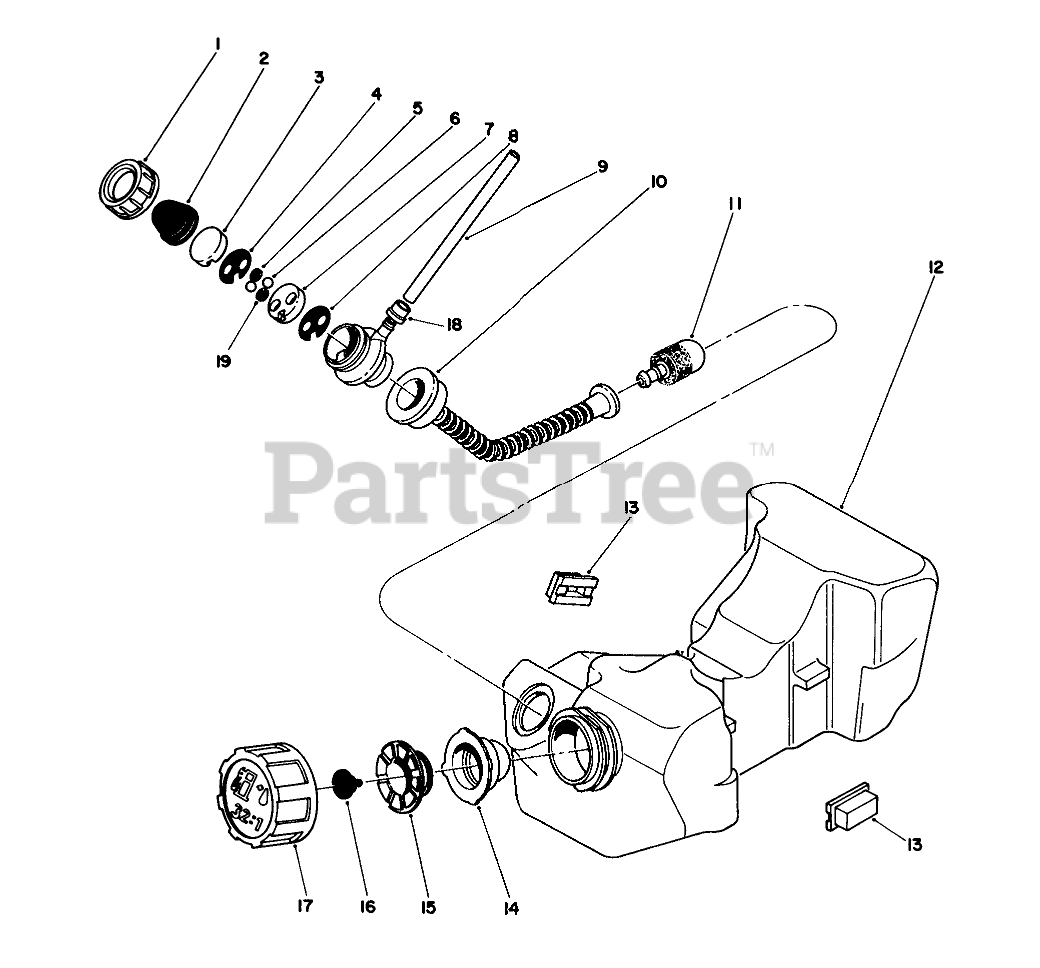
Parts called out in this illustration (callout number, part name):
1	PUMP CAP
3	SEAT VALVE
4	GASKET
5	SPONGE
7	SEAT VALVE
8	GASKET
9	Tube-Fuel
10	SUCTION HOSE
11	FUEL FILTER
12	Fuel Tank Assembly (Incl. Ref. #1-8, 10, 11, 14-17, & 19)
14	GASKET - PACKING
15	HOLDER
16	BREATHER VALVE
17	TANK CAP
19	Cushion Ball
